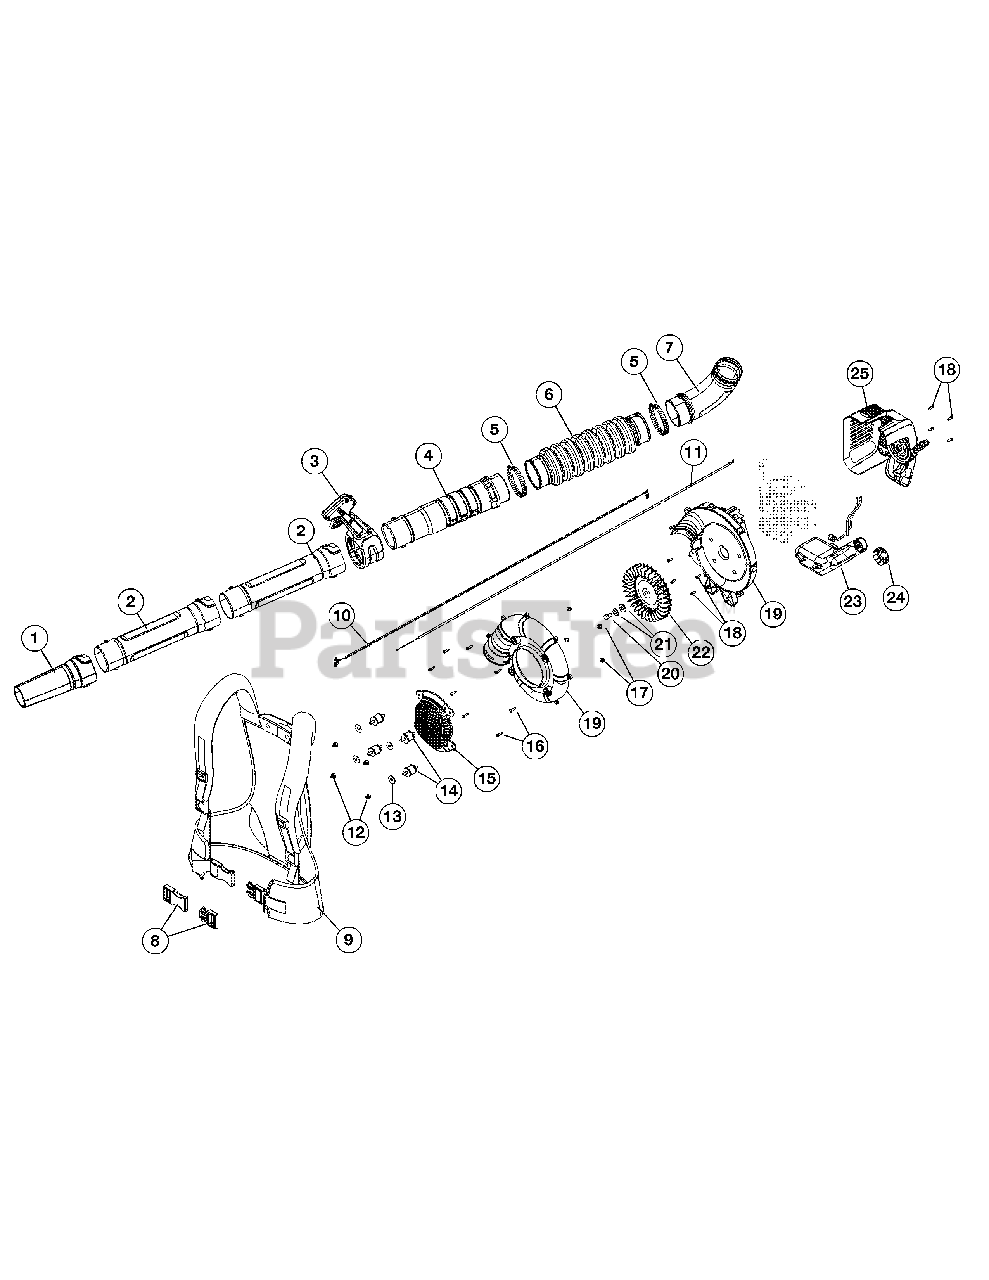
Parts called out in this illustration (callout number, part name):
1	Nozzle
2	Lower Blower Tube
3	Throttle Grip Assembly
4	Upper Blower Tube
5	Clamp
6	Flex Tube
8	Harness Clip
9	Harness
10	Lead Wire
11	Throttle Cable
12	Nut
13	Spacer
14	Insulator Mount
15	Intake Cover
17	Nut
18	Screw
19	Impeller Housing Assembly
21	Impeller Hardware
22	Impeller
23	Fuel Tank Assembly
24	Fuel Cap
25	Starter Housing Assembly
